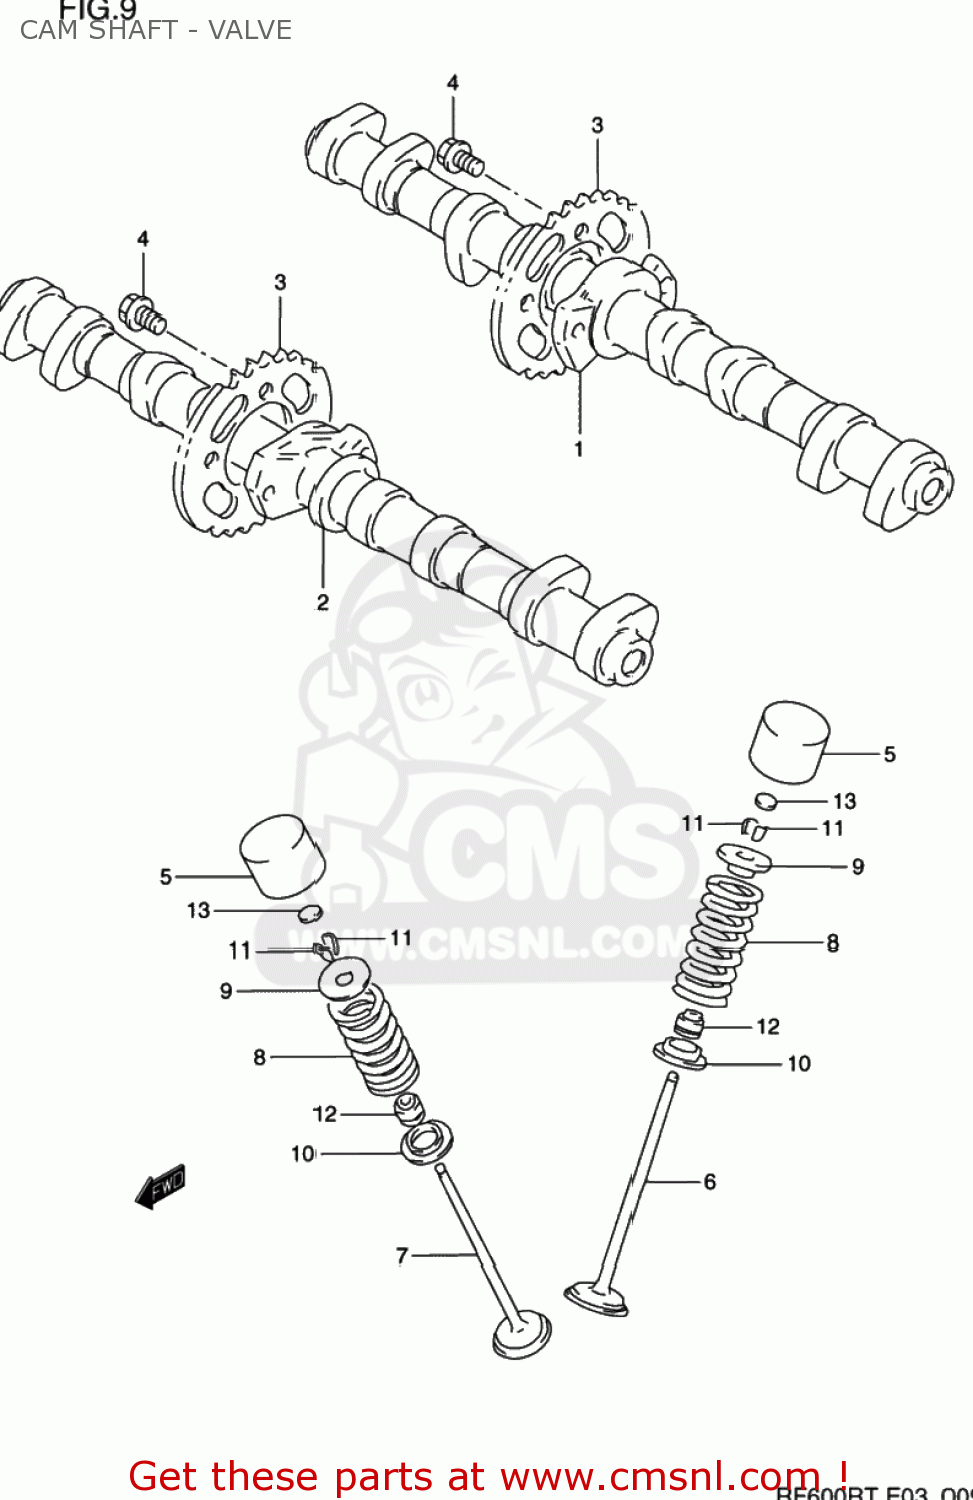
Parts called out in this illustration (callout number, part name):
1	CAMSHAFT,INTAKE
2	CAMSHAFT,EXHAUST
3	SPROCKET,CAMSHAFT
4	BOLT(7X11)
5	TAPPET
6	VALVE,INTAKE
7	VALVE,EXHAUST
8	SPRING,VALVE
9	RETAINER,VALVE SPRING
10	SEAT,VALVE SPRING
11	COTTER VALVE
12	SEAL,OIL(4.5X10X8)
13	SHIM,TAPPET
14	SHIM SET,TAPPET
15	CASE,TAPPET SHIM
